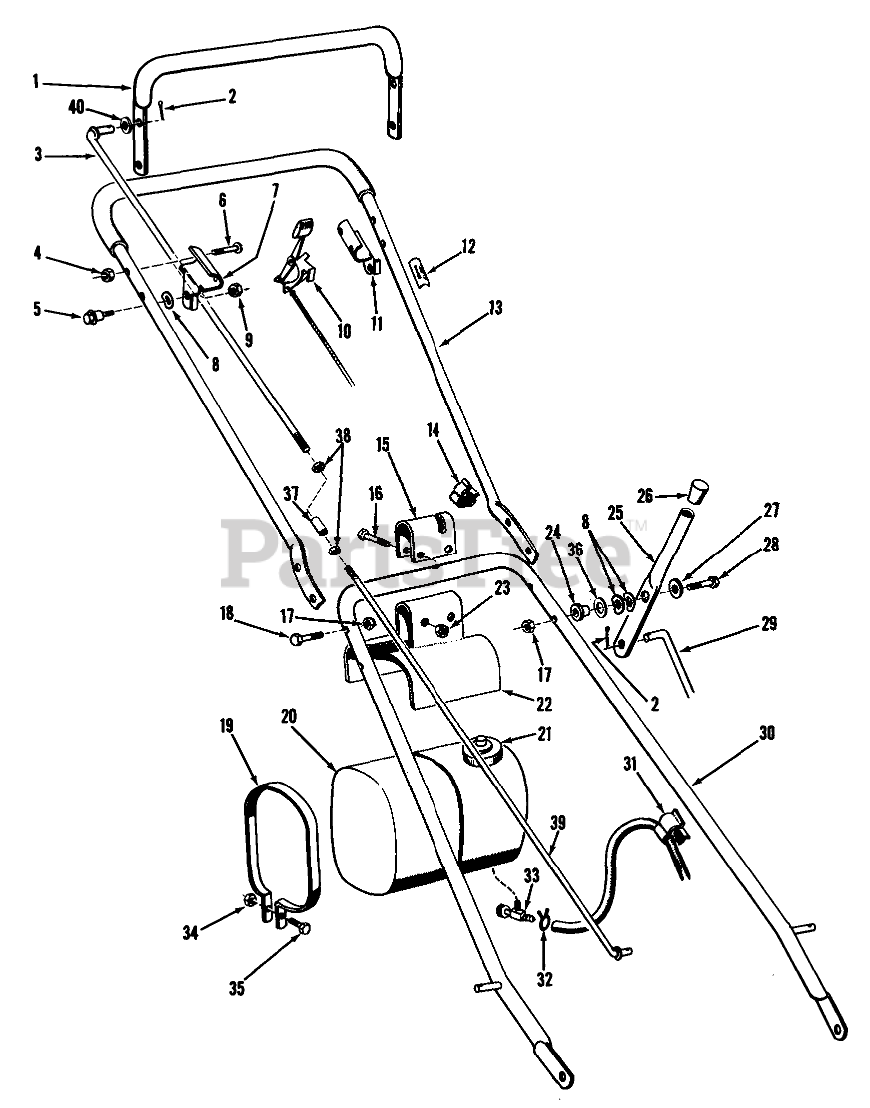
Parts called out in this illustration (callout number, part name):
1	Control Bail
2	PIN-COTTER
3	Control Rod
4	NUT-LOCK, NI
5	Screw
6	10-24X1-1/4 PAN HD MS
7	CONTROL BAIL BRACKET
8	WASHER-SPRING
9	NUT-LOCK, NI
10	Throttle Control
11	Bracket-Control Bail
12	Decal
13	Upper Handle Assy.
14	Clamp
15	Clamp, Fuel Tank
16	SCREW-HH
17	NUT-KEPS
18	SCREW-HH
19	TANK STRAP
20	Tank
22	FUEL TANK BRACKET
24	PIVOT
25	Cutter Handle
26	Button Plug
27	WASHER-FLAT
28	SCREW-HH
29	Cutter Rod 25"
30	Lower Handle
31	CLAMP
32	Clamp
33	.125 ID SHUTOFF VALVE
34	NUT-LOCK, NI
35	SCREW-HH
36	WASHER-FLAT
37	CONTROL ROD SLEEVE
38	NUT-KEPS
39	Control Rod, Lower
40	Spacer
